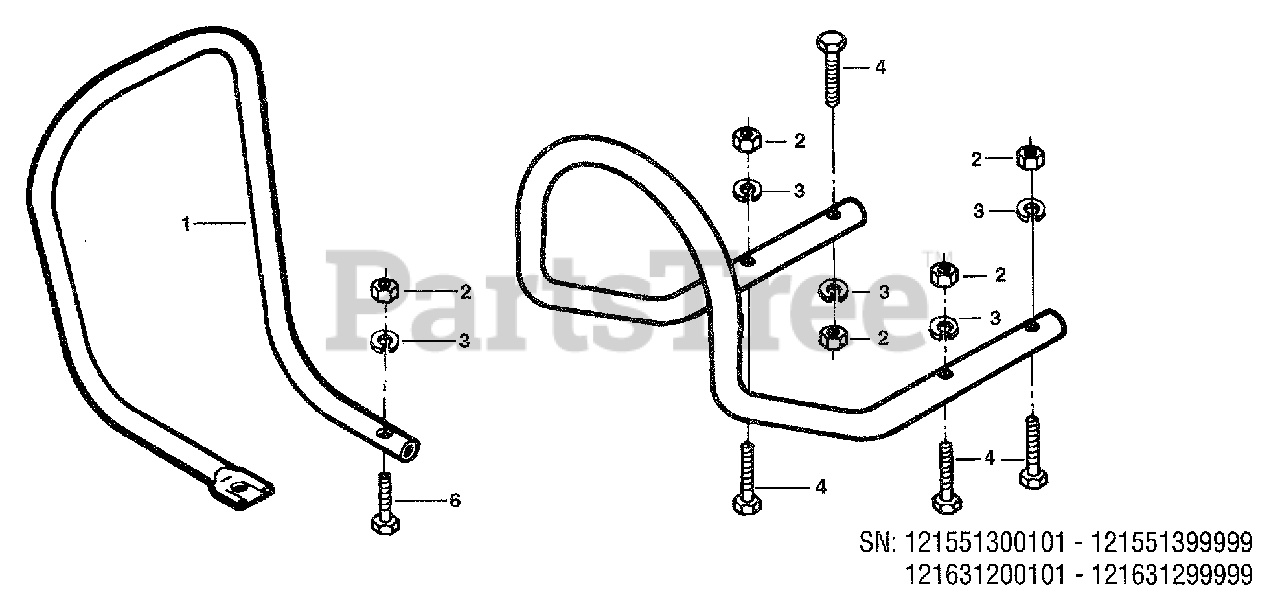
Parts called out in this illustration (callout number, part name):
1	Carburetor Guard
2	Nut-Hex Head, 5/16-18
3	Lockwasher-5/16
4	Bolt-Hex Head, 5/16-18 x 2-1/2
6	Bolt-Hex Head, 5/16-18 x 1-1/2
